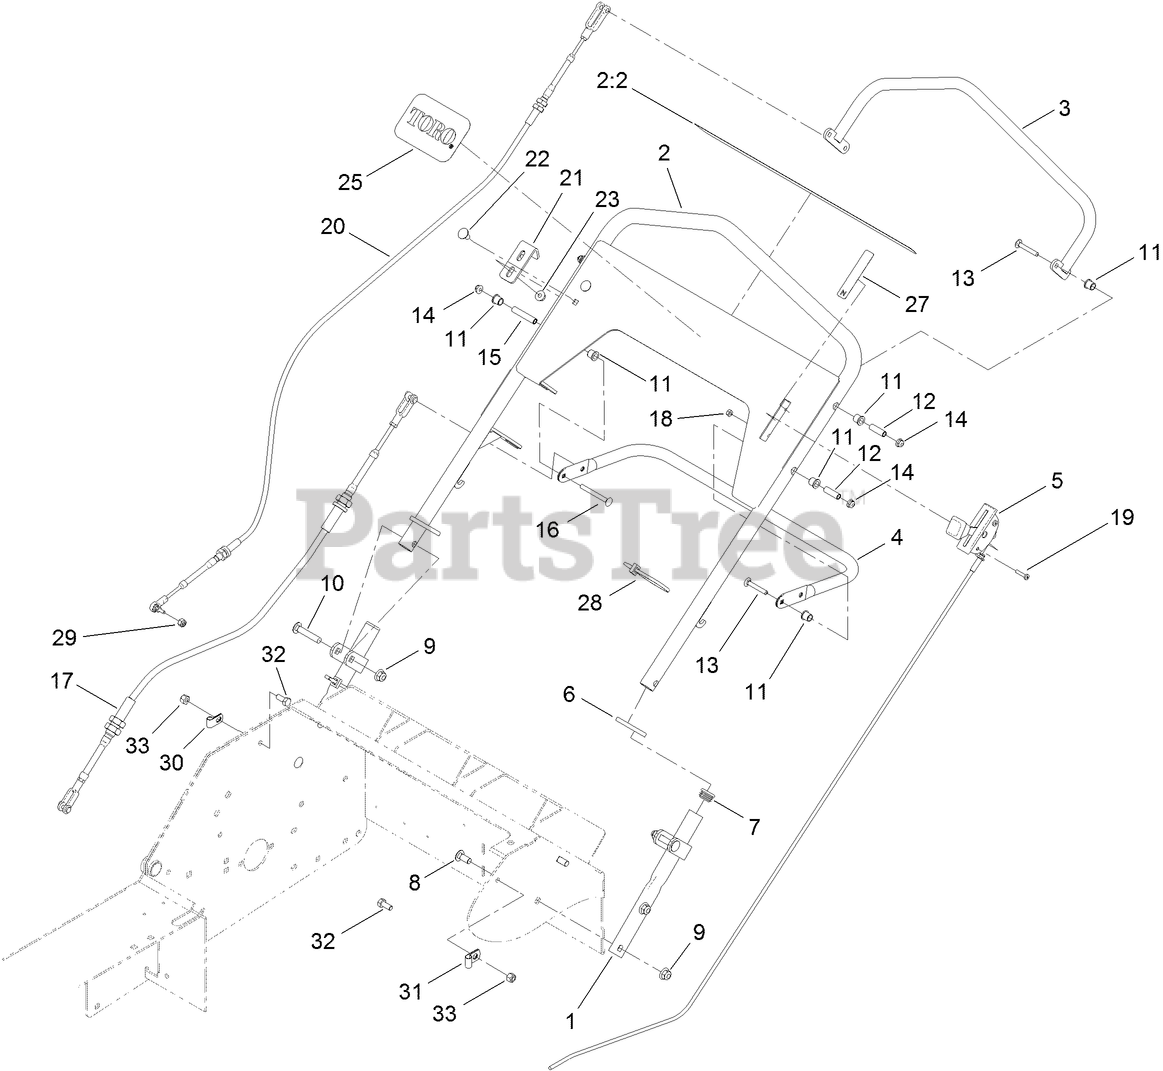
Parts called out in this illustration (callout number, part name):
1	MOUNT-HANDLE
2	HANDLE ASM
2:2	DECAL-AERATOR, CONTROL PANEL
3	TUBE-CONTROL
4	TUBE-LIFT, HANDLE
5	CONTROL-THROTTLE
6	RING-HANDLE LOCK
8	BOLT-CARR
9	NUT-HF, NI
10	SCREW-CARR
11	BEARING
12	BUSHING-PIVOT
13	SCREW-CARR
14	NUT-HF
15	BUSHING-PIVOT
16	SCREW-CARR
18	NUT-LOCK, NI
19	SCREW-PPH
21	ANGLE-STOP
22	SCREW-CARR
23	NUT-HF, NI
27	DECAL-THROTTLE, CHOKE
28	TIE-CABLE
29	NUT-LOCK
30	CLAMP-R
31	CLAMP-R
32	SCREW-HH
33	NUT-LOCK, NI
